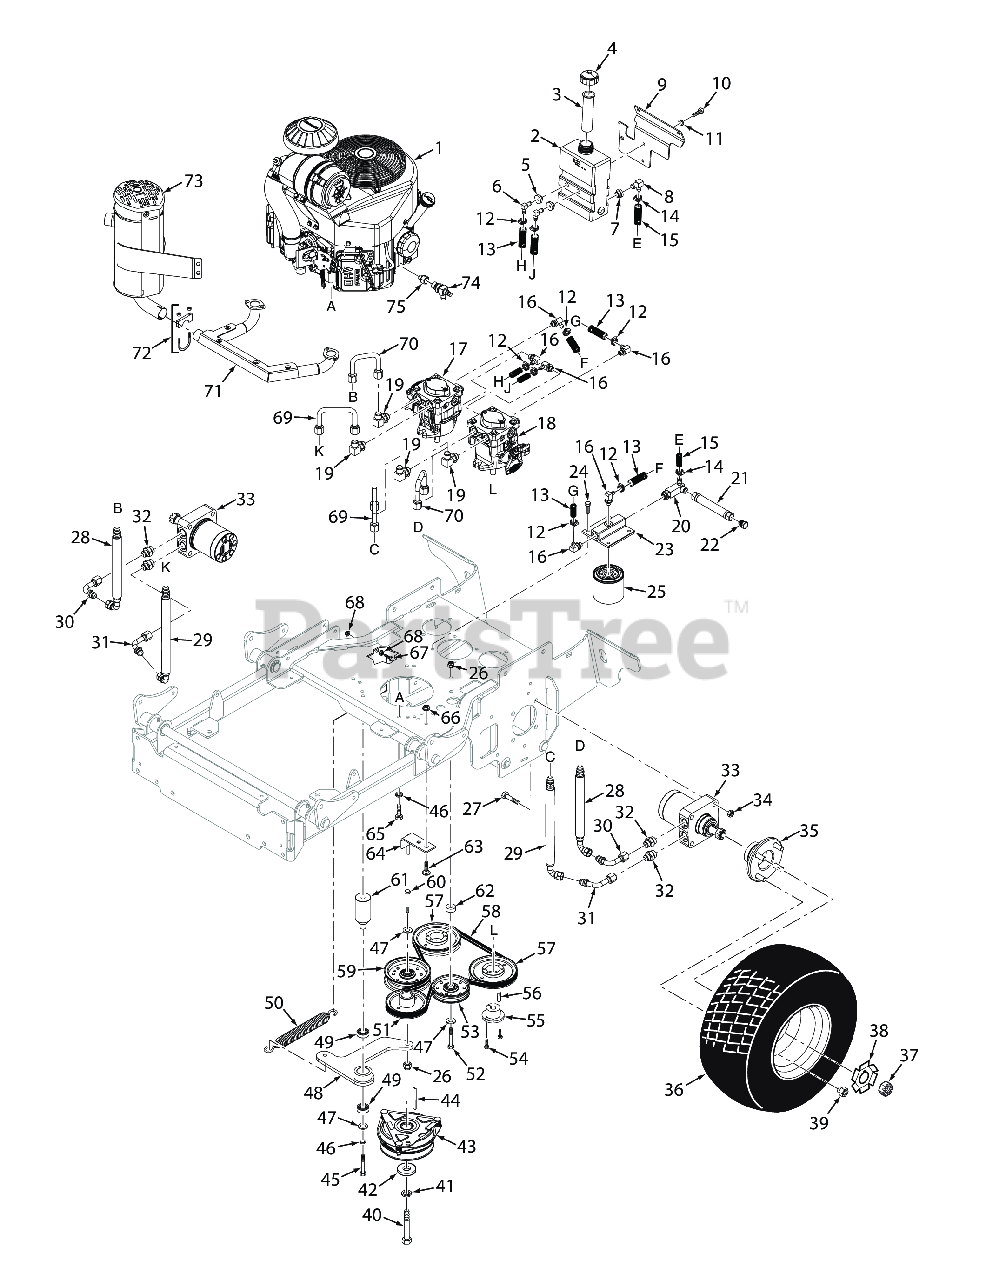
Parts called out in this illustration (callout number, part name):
1	Engine, 15hp Kawasaki FS541V
1	Engine, 19hp Kawasaki FX600V
2	Hydro Tank Assy., SVRII
3	Insert, Filler Neck
4	CAP, HYDRAULIC TANK
5	Bushing, 0.56" Dia. Viton
6	Elbow, 90 Degree, 9/16-18 JIC x 9/16 O-Ring
7	Bushing, 0.78" Dia. Viton
8	Fitting, 90 Degree - 1/2" Hose
9	Bracket, Hydro Tank Mounting
10	BOLT, SERRATED FLANGE HEX HEAD 5/16-18 X 3/4"
11	Lockwasher, 5/16 (.317 x .586 x .078) Helical Spring
12	Clamp, .69" Max. / .25" Min. Dia.
13	Hose, 3/8" ID - 10-1/4" Long (Order By The Inch)
14	Clamp, Cable 3/4" I.D.
15	Hose Assembly, 1/2" ID (Oil Reservoir to Filter Base)
16	Elbow, 90 Degree - 9/16" O-Ring x 3/8" Hose
17	Pump, LH - 10cc (36 Only)
18	Pump, RH - 10cc (36 Only)
19	Elbow, 90 Degree 3/4-16 JIC x 3/4-16 O-Ring
20	Tee, 3/4" O-Ring
21	Drain Hose Assy.
22	Plug, JIC 3/4-16 UNF
23	Filter Head Assembly
24	BOLT, SERRATED FLANGE HEX HEAD 5/16-18 X 3/4"
25	OIL FILTER, SPECIAL
26	HEX NUT, ELASTIC STOP LOCK, 3/8-16
27	Bolt, Hex Hd. 1/2-13 x 2-1/2" (lower)
28	Hose Assy., 11-1/4"
29	Hose Assy., 13-1/4"
30	Tube Assy., 1/2 x 2 x 2"
31	Tube Assy., 1/2 x 2 x 3-1/4"
32	TUBE UNION, 3/4-16 JIC TO 7/8-14 "O" RING
33	Wheel Motor
33	Key, Woodruff 3/16 x 3/4"
34	Locknut, Hex 1/2-13 Center Lock
35	Wheel Hub Assembly
35	Bolt, Serr. Flange 1/2-20 x 4.563"
36	Wheel Assy., 20 x 8 - 10
36	Tire, 20 x 8 - 10
36	Rim w/ Valve
37	HEX CASTLE NUT, 3/4-28 UNEF
38	Lock Washer, Wheel Motor
39	Wheel Nut, 1/2-20 x 13/16
40	Bolt, Hex Head 7/16-20 x 2-1/4" w/Patch (Kawasaki)
41	Lockwasher, 7/16� Spring
42	Flatwasher, 7/16-.469 x 1.75 x .25 (48, 52)
43	Clutch w/Tag GT2.5-FE02 (48 / 52)
44	Key, 1/4 x 1/4 x 3-1/2"
45	Capscrew, Hex Head 3/8-16 x 3-3/4"
46	Lockwasher, 3/8" Spring, Kawasaki FX / FS
47	Flatwasher, 3/8 (.391 x .938 x .105 HD) Grade 8
48	Idler Arm Assy., Pump Drive - SVRII-36
49	BEARINGS, BALL, NEUTRAL RETURN
50	Spring, Transmission Idler
51	Pulley, 4-3/4" OD - 1.125 Bore
52	Bolt, Hex Head 3/8-16 x 2-1/4" - 61"
53	Pulley, Idler 4� Dia.
54	Bolt, Hex Head 1/4-20 x 1" Grade 8 Black
55	Hub, Tapered, 15mm Bore
56	KEY, 5 MM X 5 MM X 25 MM
57	Pulley, 5.45 OD - Tapered Bore"
58	Belt, Pump Drive - SVRII-36
59	Pulley, 4" Dia. Idler
60	BOLT, HEX HEAD, 5/16-18 X 2-1/4
61	Pivot, Idler
62	Spacer, Idler Pulley - SFZ61
63	Bolt, 5/16-18 x .75 RHSN Carriage
64	ANTI-ROTATION WLMT, SVRII
65	Bolt, Hex Head 3/8-16 x 1-1/4", Kawasaki FX / FS
66	Nut, Serrated Flange 5/16-18 (Right Front Engine Mounting, Briggs and Kohler Only)
67	Bolt, Hex Head 3/8-16 x 1-1/2" Grade 8 Black
68	NUT, 3/8-16 SERRATED FLANGE HEX HEAD
69	1/2" U-Tube Assembly, 4" Wide
70	1/2" U-Tube Assembly, 3" Wide
71	Exhaust Manifold, 15 HP Kawasaki FS
72	Muffler Clamp
73	Muffler, Kawasaki (FS481, FS541, FS600)
74	Oil Drain, SVRII-36
74	Tubing, Oil Drain (order by inch)
75	Wire Harness, SVRII Recoil Start
